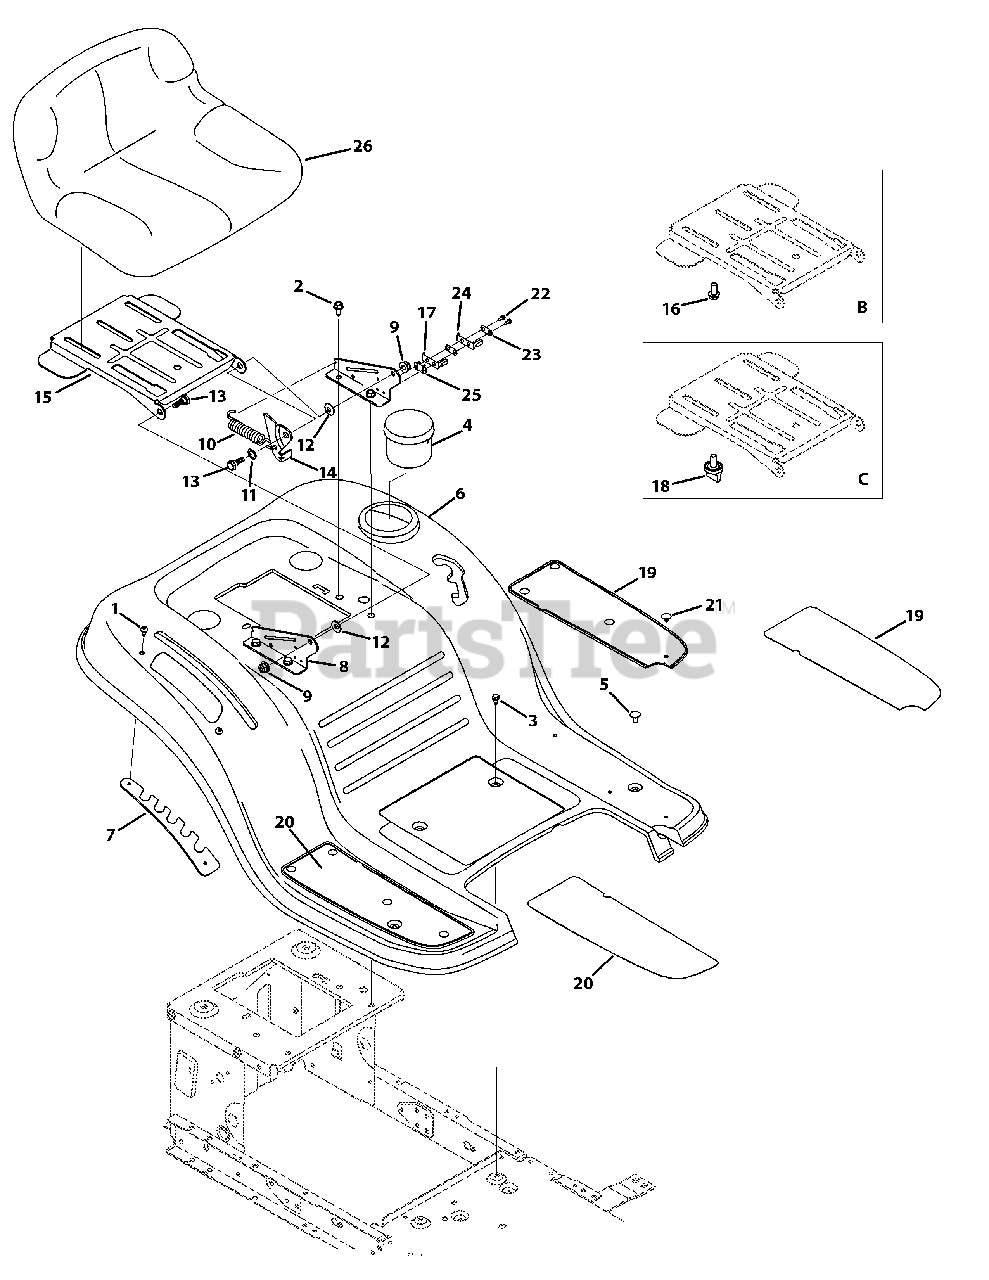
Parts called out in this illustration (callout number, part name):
1	Screw, 1/4-20 x .500
2	Screw, 5/16-18 x .750
3	Screw Pan Torx Head, 1/4-20 x 5.00
4	Cup Holder
5	Screw Carriage, 1/4-20 x .62
6	Fender - Red
6	Fender - Black
7	Lift Adjuster Bracket - Powder Black
8	Seat Mount Bracket - Powder Black
9	Flangelock Nut, 5/16-18
10	Extension Springing
11	Flat Washerer, .510x .750 x .033
12	Bell Washerer, .340 x .872 x .060
13	Shoulder Screw, 5/16-18 x .437 x .268
14	Lift Seat Bracket
15	Pivot Seat Manual Adjust Bracket
16	Hex Head Flange, 3/8-16 x .875
17	Inner Seat Springing
18	Knob, 3/8-16 x .875
19	Foot Pad, LH
19	Foot Pad, Abrasive, LH
20	Foot Pad, RH
20	Foot Pad, Abrasive, RH
21	Ratchet Clip, 250 x .500
22	Screw, 8-18 x .500
23	Insulator Plate
24	Outer Seat Springing
25	Insulator Boss Plate
26	Med Back Seat, Black, Set-up B or C
